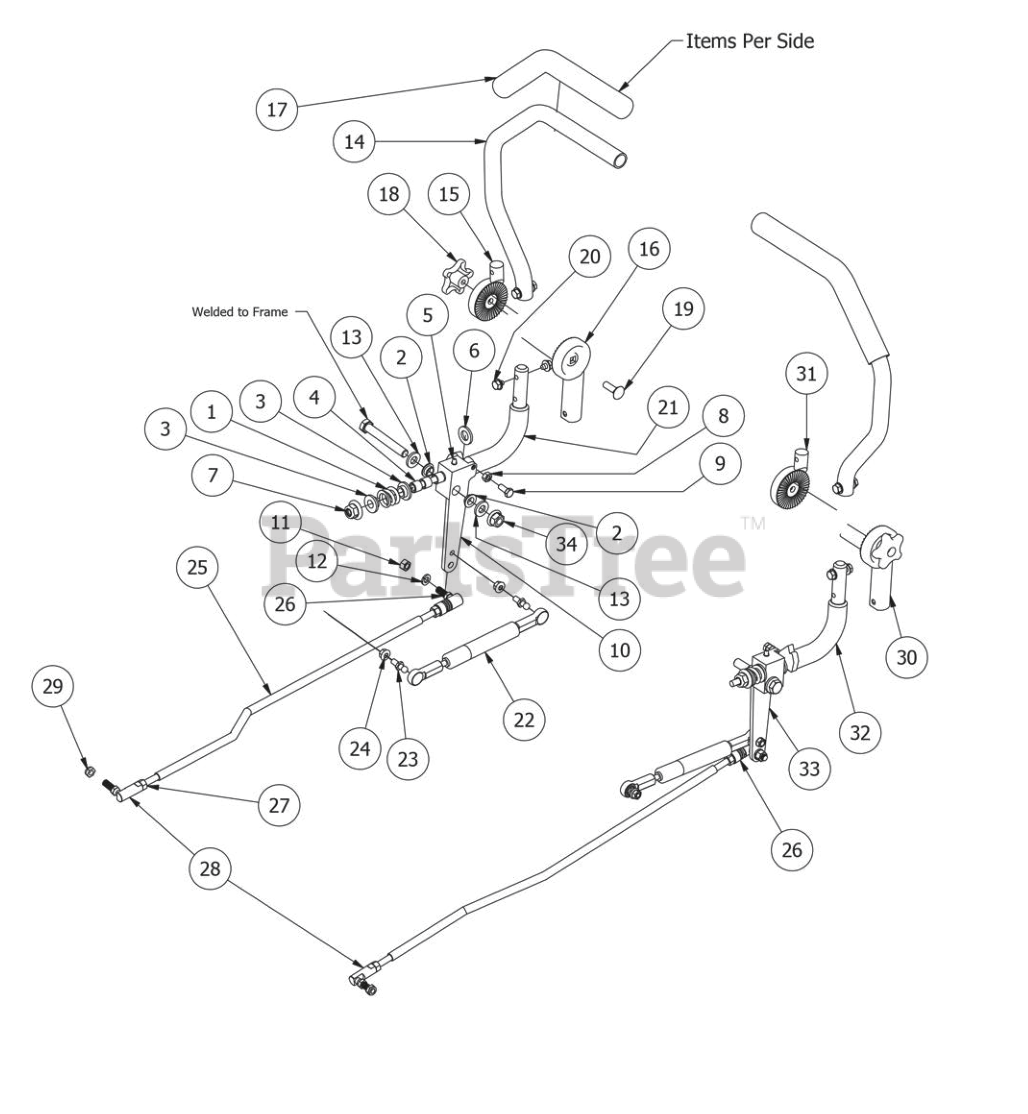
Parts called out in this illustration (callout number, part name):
1	Drive Lever Spring
2	Bushing for 2012 Drive Arms
3	.515 ID Nylon Shoulder Washer
4	.507 ID Nylon Bushing
5	1/4" Drive in Grease Fitting
6	.635 ID Plastic Washer
7	1/2-13 Nylon Flange Nut-Orange
9	5/16" x 3/4" Hex Bolt
10	Drive Arm Lever Housing (Left)
11	3/8" Fine Threaded Jam Nut
12	3/8" Lock Washer
13	.505x1x .125 Oil Impregnated washer
14	Upper Tube-Adjustable Steering
15	Upper adjuster-Steering Arm- Left
16	Lower Adjuster - Steering Arm- Left
17	Black Steering Grip
18	Black Knob for Adjustable Steering Arm
19	3/8" x 1 1/4" Carriage Bolt
20	5/16-18 1/2 HWH Bolt-Steering
21	Steering Arm Elbow - Left
22	Steering Damper for Outlaw
23	10mm Damper Ball Stud-Steering
24	5/16" Flange Nut
25	outlaw XP Push Rod
26	Quick Release Ball Joint
27	3/8" Fine Threaded Jam Nut
28	3/8-24 Ball Joint
29	3/8-24 Nylon Insert jam locknut
30	Lower Adjuster - Steering Arm- Right
31	Upper Adjust Steering Arm- Right
32	Steering Arm Elbow - Right
33	Drive Arm Lever Housing Right
34	1/2-13 Hex Flange (GR.G) ZC
